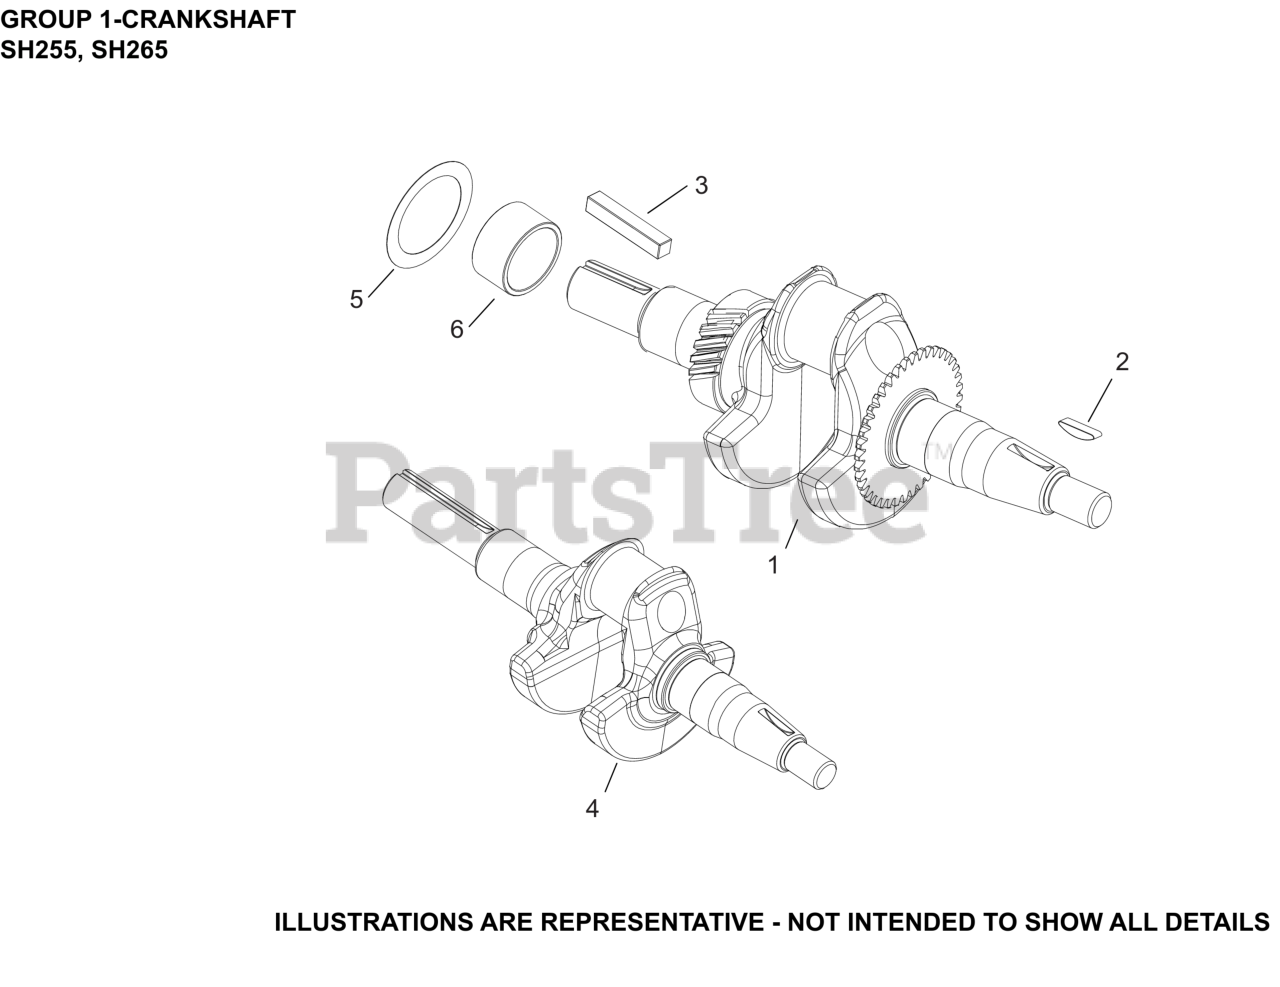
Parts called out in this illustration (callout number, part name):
1	CRANKSHAFT ASSEMBLY
2	KEY, FLYWHEEL
3	KEY, SQUARE
